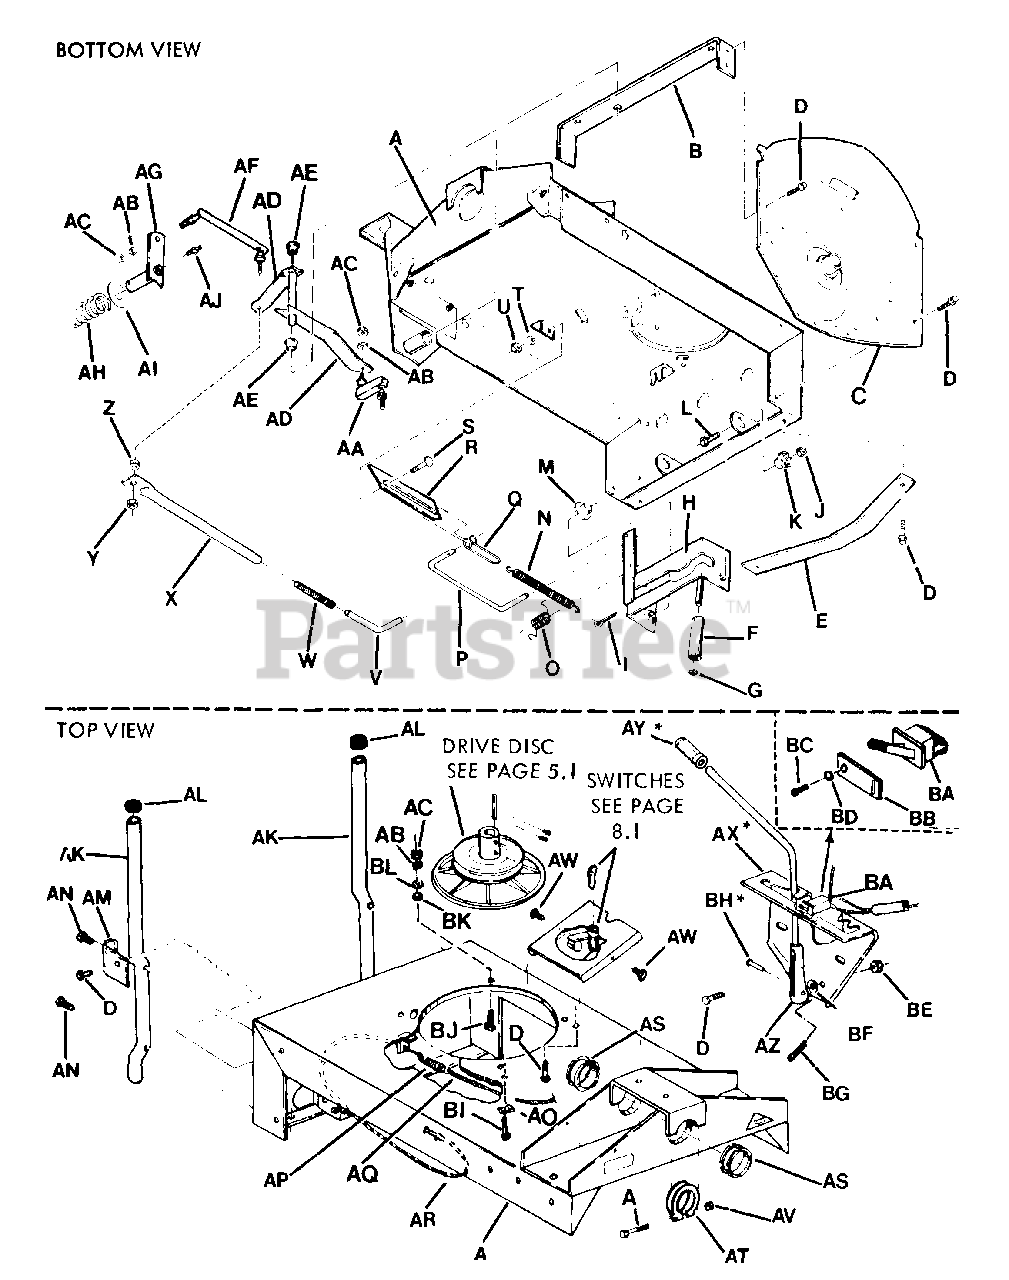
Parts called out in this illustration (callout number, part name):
A	MAIN-CASE
B	BRACE, CROSS
C	FENDER, L.H.
D	SCREW, SELF-TAPPING 5/16-18 x 5/8
E	PLATE, HITCH
G	RING, RETAINING
H	LIFT, Yoke
I	COTTER-PIN, 3/16 x 3/4
J	NUT, HEX CENTER LOCK 5/16-24
K	BEARING, YOKE (RIGHT HAND)
L	SCREW, HEX HEAD CAP 5/16F x 3/4
M	WASHER, THRUST
N	SPRING
O	SPRING
P	ROD, CLUTCH
Q	CLEVIS, CLUTCH
R	GUIDE, ROD
S	BOLT, CARRIAGE 3/8-16 x 3/4
T	WASHER, 3/8 LOCK
U	NUT, 3/8-16 HEX
V	ROD
W	SPRING
Y	NUT, 5/16-24 HEX LOCK
Z	ROLLER
AA	LINK, SHIFT (SHORT )
AB	WASHER, 5/16 LOCK
AC	NUT, 5/16-24 HEX
AD	ARM, SHIFT
AE	BUSHING, NYLON
AF	LINK, SHIFT (LONG)
AG	ARM, SHIFT HANDLE
AH	SPRING, SHIFT HANDLE
AI	WASHER, THRUST
AJ	FITTING, Lube (Press fit for .187 hole-no ball)
AK	BUMPER, REAR
AL	CAP, BUMPER
AM	SUPPORT, BUMPER
AN	SCREW, SELF-TAPPING 5/16-18 x 1 1/2
AO	WASHER (CLIP TECUMSEH 5-6 HP)
AP	SPRING, BRAKE CABLE
AQ	CABLE, BRAKE
AR	HOUSING, BRAKE CABLE
AS	GROMMET, MAIN TUBE
AT	CLAMP, MAIN TUBE
AV	NUT, 5/16-24 FLANGE LOCK
AW	SCREW, SELF-TAPPING 1/4-20 x 3/8
AX	DETENT, SHIFT
AY	GRIP, SHIFT HANDLE
AZ	HANDLE, SHIFT
BA	SWITCH, INTERLOCK - ASSEMBLY
BB	PROTECTOR, SWITCH
BC	WASHER, f10 SAE
BD	SCREW, #10-24 x 1/2" Hex Washer Self-Tap (Torx)
BE	NUT, 5/16-18 HEX
BF	WASHER, THRUST
BG	COTTER-PIN 3/32 x 3/4
BH	PIN, CLEVIS
BI	SCREW, HEX WASHER SELF TAPPING 3/8C x 1
BJ	SCREW, HEX HEAD CAP 5/16F x 1 1/2
BK	RETAINER, BOLT 5/16
BL	WASHER, SAE 5/16
